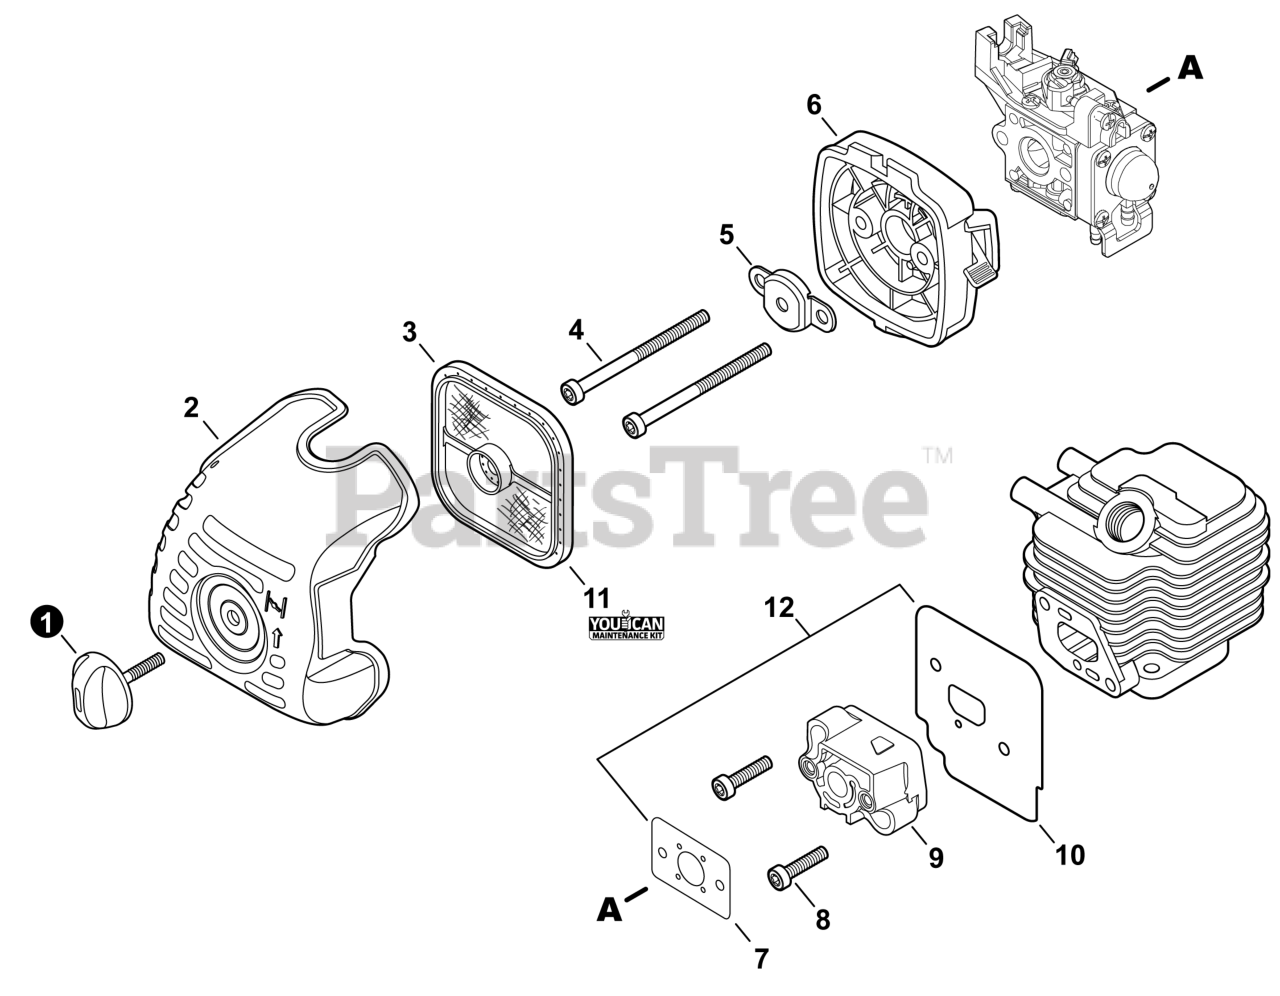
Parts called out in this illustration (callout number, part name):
1	THUMBSCREW
2	COVER, AIR FILTER
3	FILTER, AIR - DOUBLE LAYER
4	BOLT, TORX 5x55
5	PLATE, PREVENT
6	CASE ASSY, AIR FILTER
7	GASKET, INTAKE
8	BOLT, TORX 5x20
9	INSULATOR, INTAKE
10	HEAT SHIELD, INTAKE
11	TUNE-UP KIT - YOUCANT
12	GASKET KIT: ENGINE, INTAKE, EXHAUST
